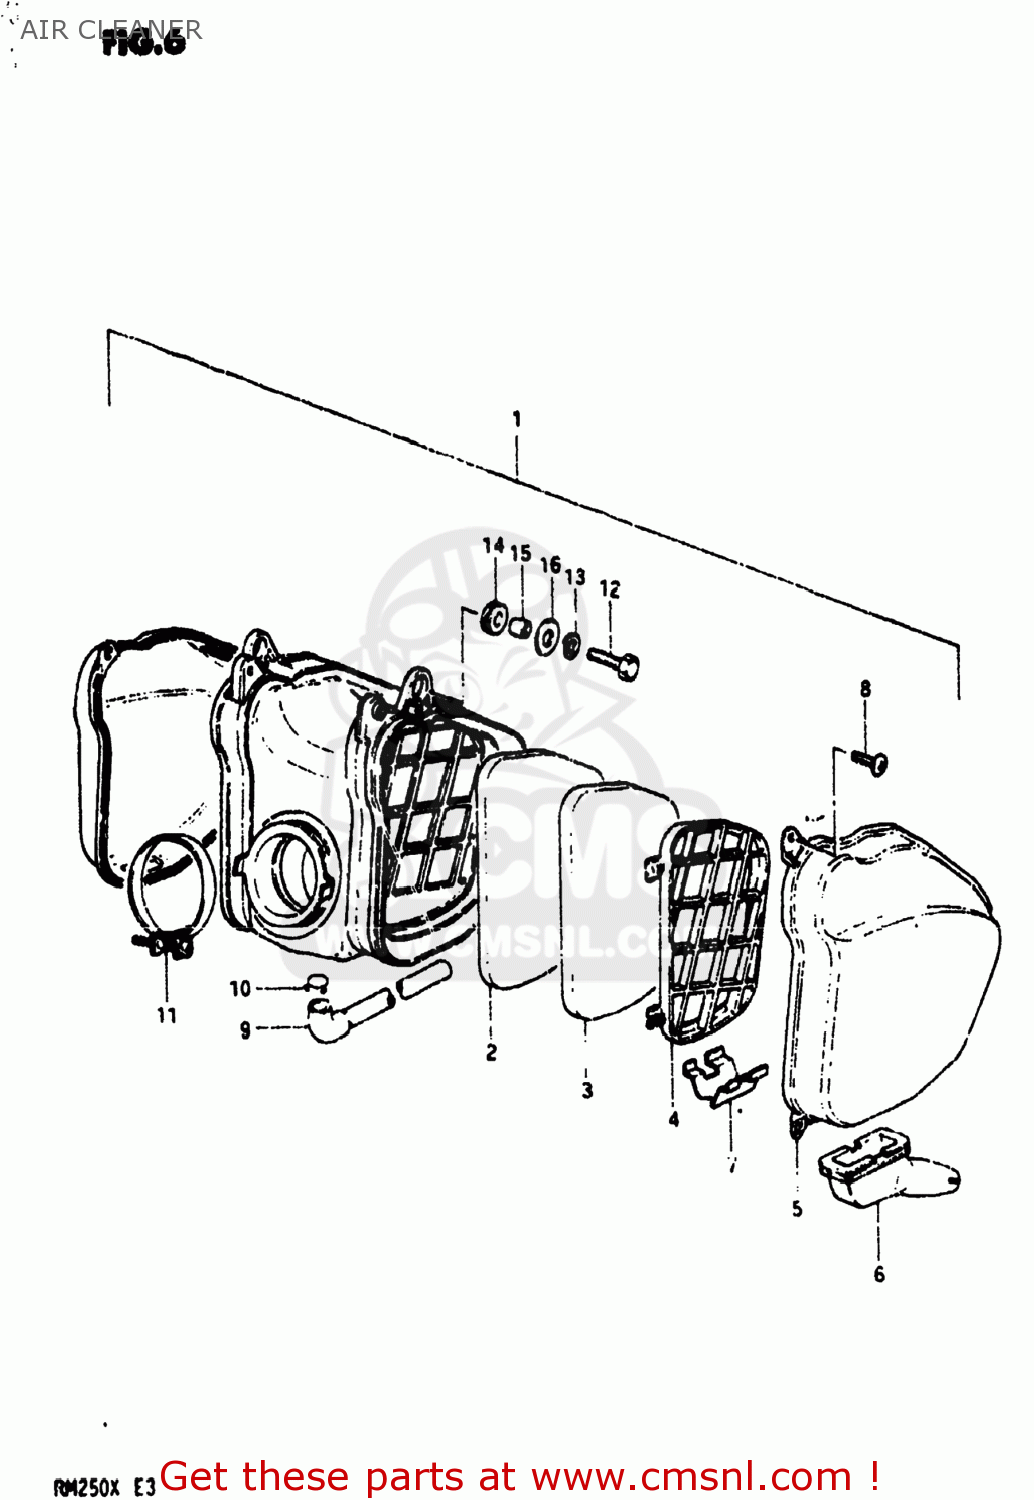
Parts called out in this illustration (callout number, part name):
1	CLEANER ASSEMBLY,AIR
2	FILTER
3	ELEMENT,AIR CLEANER
4	HOLDER,FILTER
5	CAP,AIR CLEANER
6	TUBE, DRAIN
7	DRAIN STOPPER
8	SCREW
9	DRAIN TUBE
10	CLIP
11	CLAMP
12	BOLT
13	LOCK WASHER
14	CUSHION
15	SPACER (7X9X7)
16	WASHER
